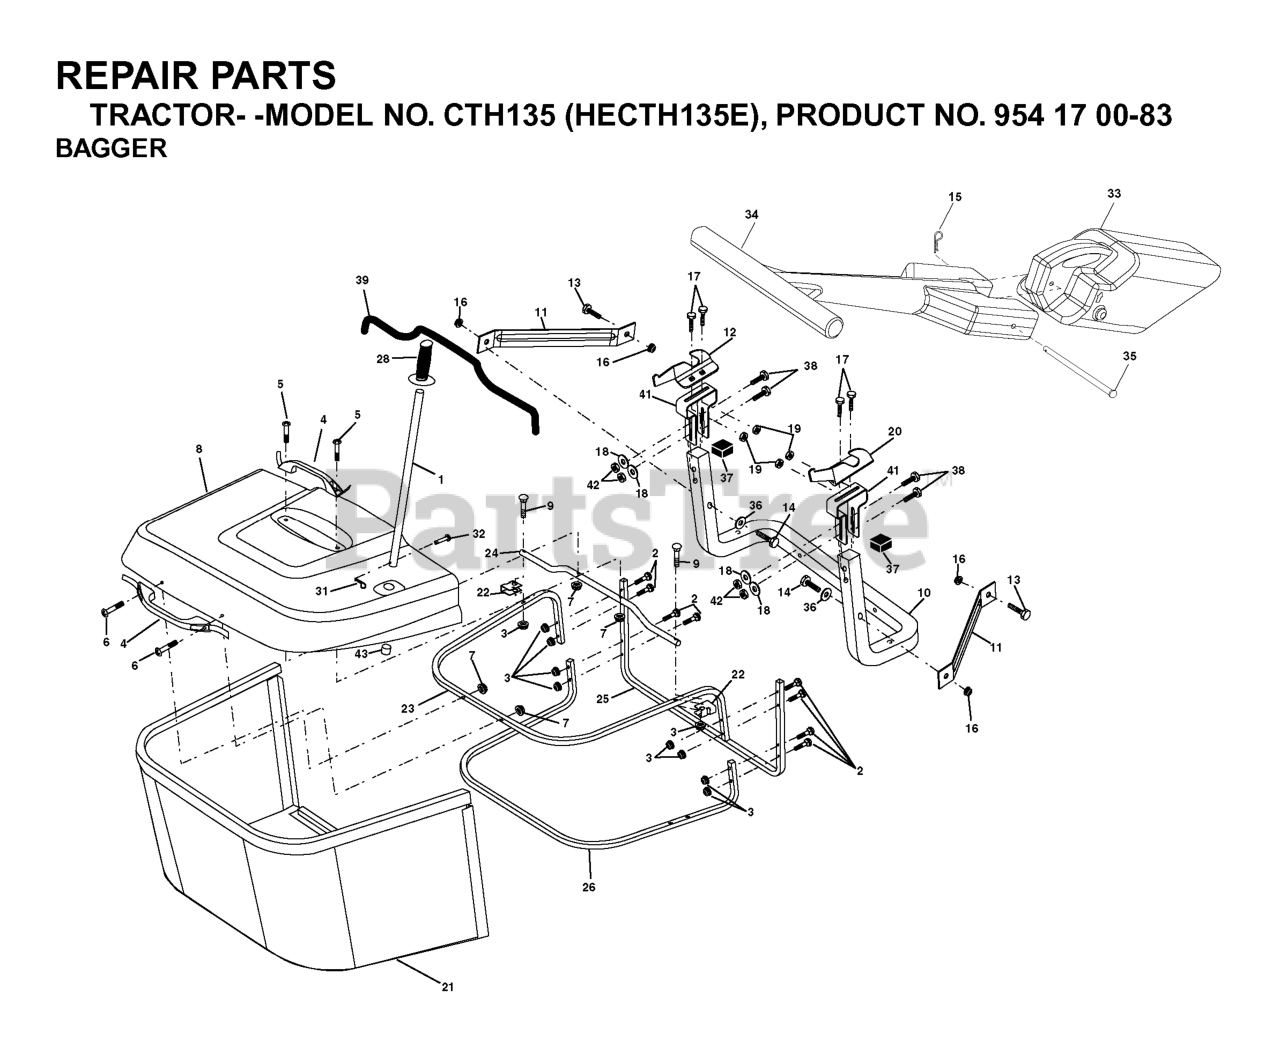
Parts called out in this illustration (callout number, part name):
1	TUBE HANDLE
2	Bolt Carriage 1/4-20 x 2.0 Gr.5
3	NUT T
4	HANDLE.BAGGER.W/LVRS.BLK.CRD
5	SCREW.PAN.HEAD
6	REPL BY 532 75 00-29
8	COVER.PNT.BGR.CRD.WSLOTS.MS668
9	Bolt Carriage 1/4-20 x 2.25d x Gr.5
10	TUBE
11	BRACKET.SUPPORT.UPPER.BAG.CRD
14	BOLT-HEX EAK
15	RETAINER-SPRNG RB
16	NUT LOCK FLG 3/8-16 UNC
17	RP BOLT 5/16-18 X3/4 ZN/YEL GR
18	WASHER M
19	NUT LOCK HEX FLANGE 5/16-18
20	BRACKET
21	GRASS BAG
22	BRKT.SIDE.BAG.CRD
23	TUBE.UPPER.BAG.CRD
24	TUBE.PIVOT.BAG.CRD.BLACK
26	TUBE.LOWER.BAG.CRD
28	GRIP.HANDLE.BLACK
31	RETAINER M
32	RIVET,DRILLED
33	PLUG.MULCHER.92 CRD
34	HANDLE.MULCHER.92.CRD (2 2)
36	WASHER
37	Plug Support Bagger CRD
38	BOLT.5/16-18X2.5
39	SEAL.TRIM.37'
41	BRKT.VERT.ADJ.BAGGER.CRD
42	NUT.71038.31-18.HEX.NYLOCK
43	PLUG, TUBING END
